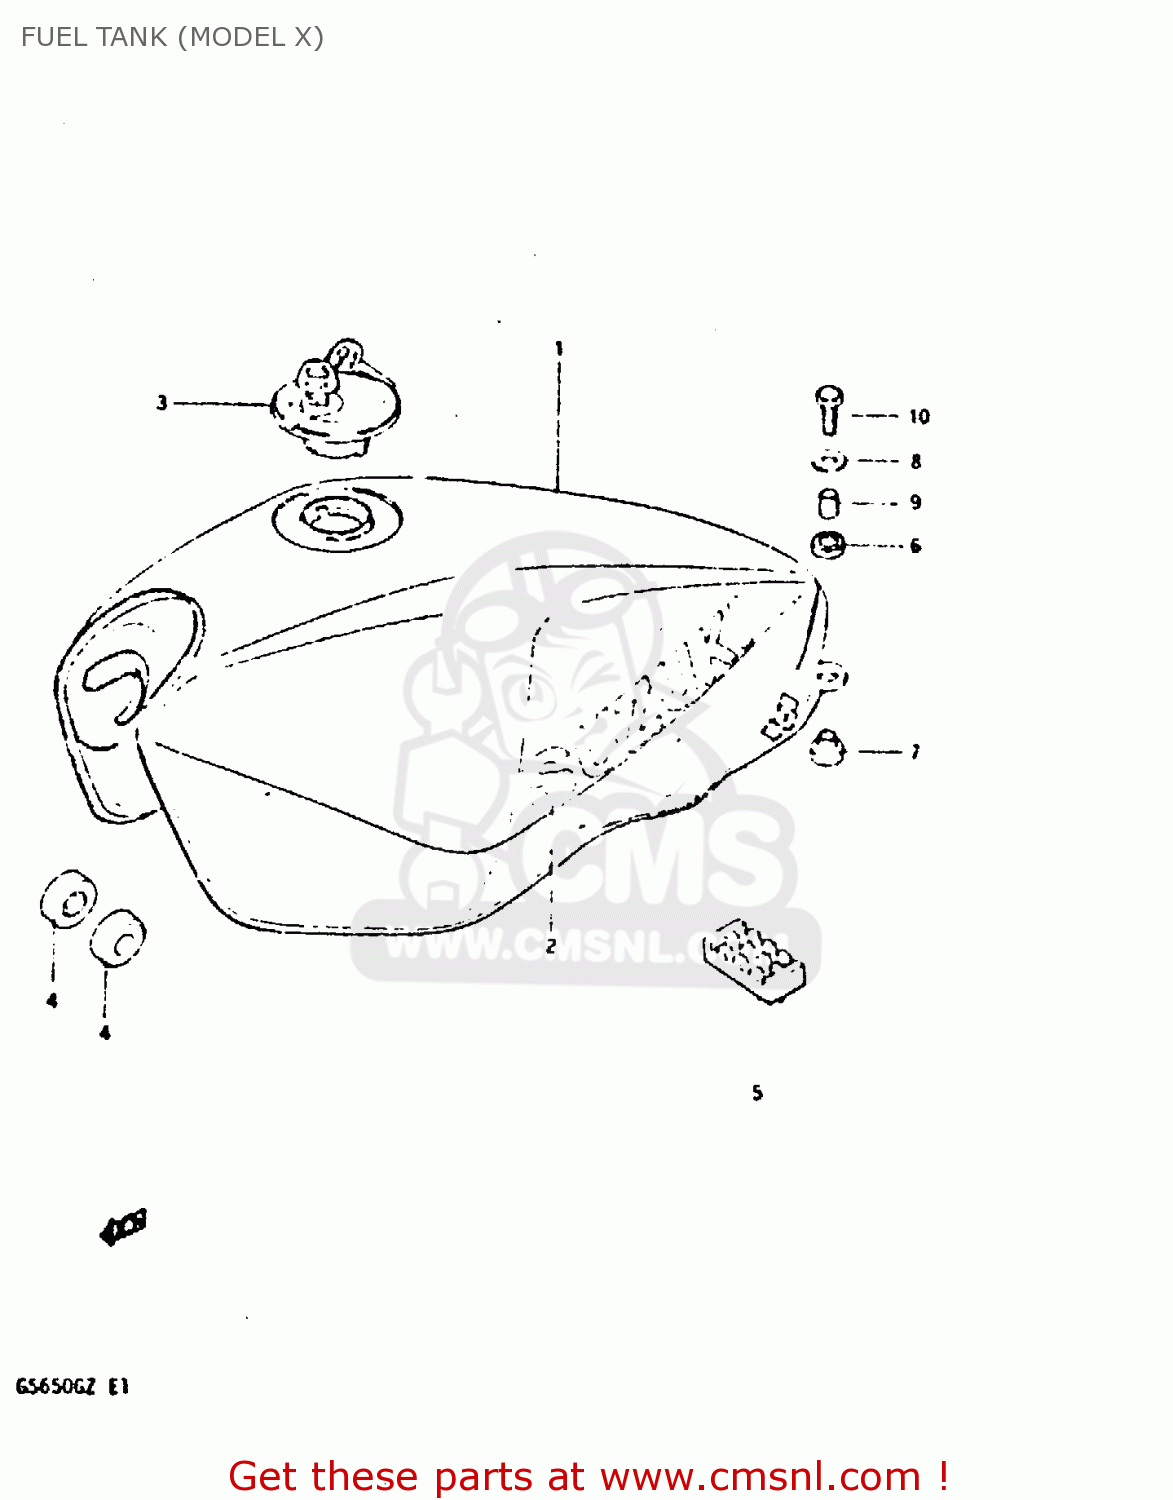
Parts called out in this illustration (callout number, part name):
1	TANK, FUEL (SILVER)
2	EMBLEM
3	CAP SET,FUEL TANK
4	CUSHION
5	CUSHION,FUEL TANK CTR
6	CUSHION
7	CUSHION
8	WASHER (6.5X24X1.6)
9	SPACER
10	BOLT
